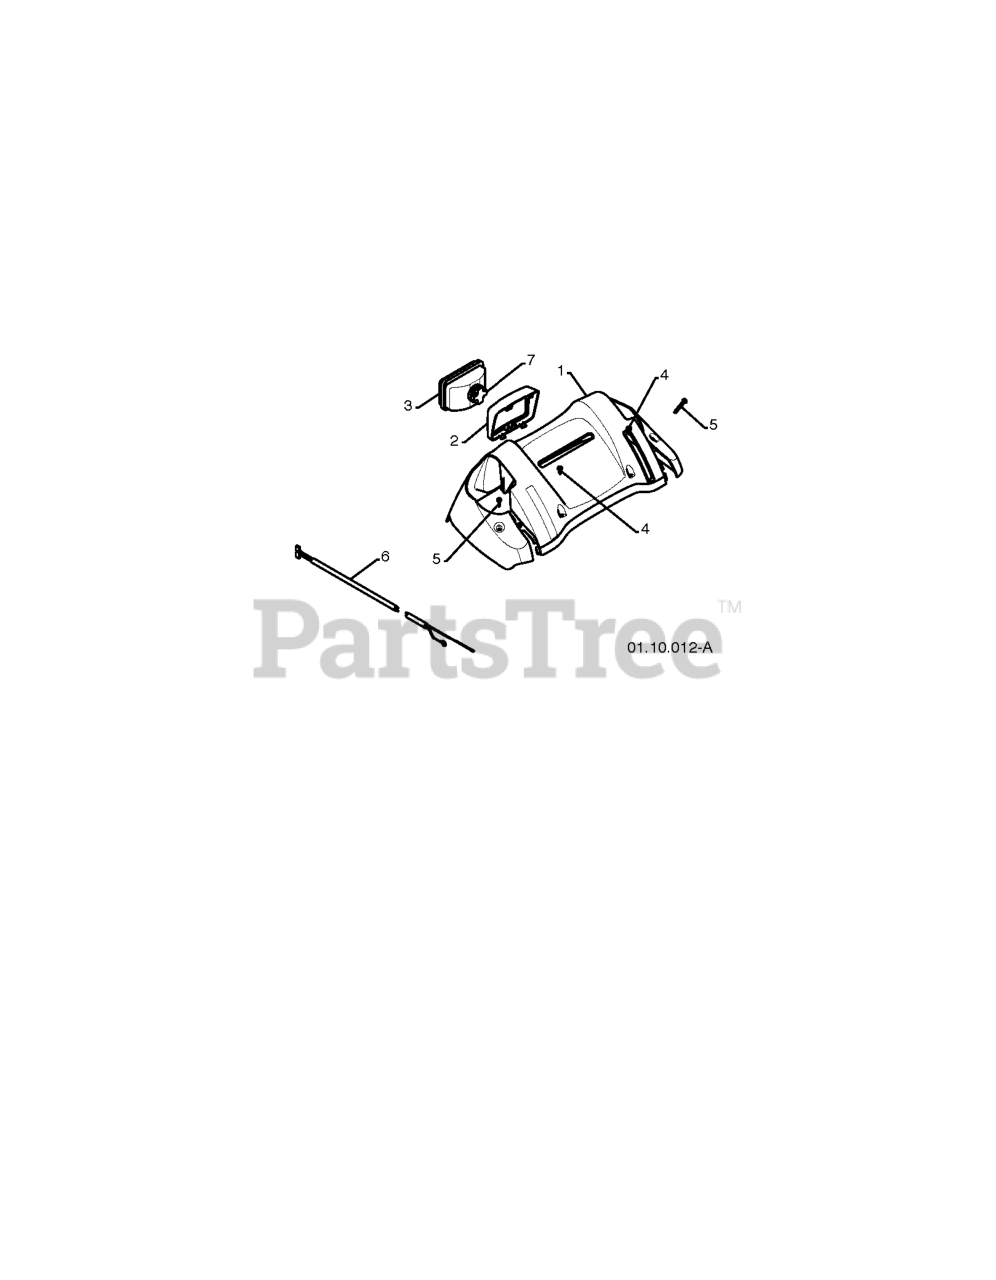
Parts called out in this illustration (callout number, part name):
1	PANEL.CONSOLE.FLOOD.LIGHT.GREY
2	BEZEL.HEADLIGHT
3	RP.HEADLIGHT.FLOOD.SNOW
4	SCREW, HEX HEAD, TAPPING
5	SCREW, HEX HD TAPPING #10-24 1
6	HARNESS, HEADLIGHT (FLOOD)
7	BULB.HEADLIGHT.FLOOD.1156-12V
